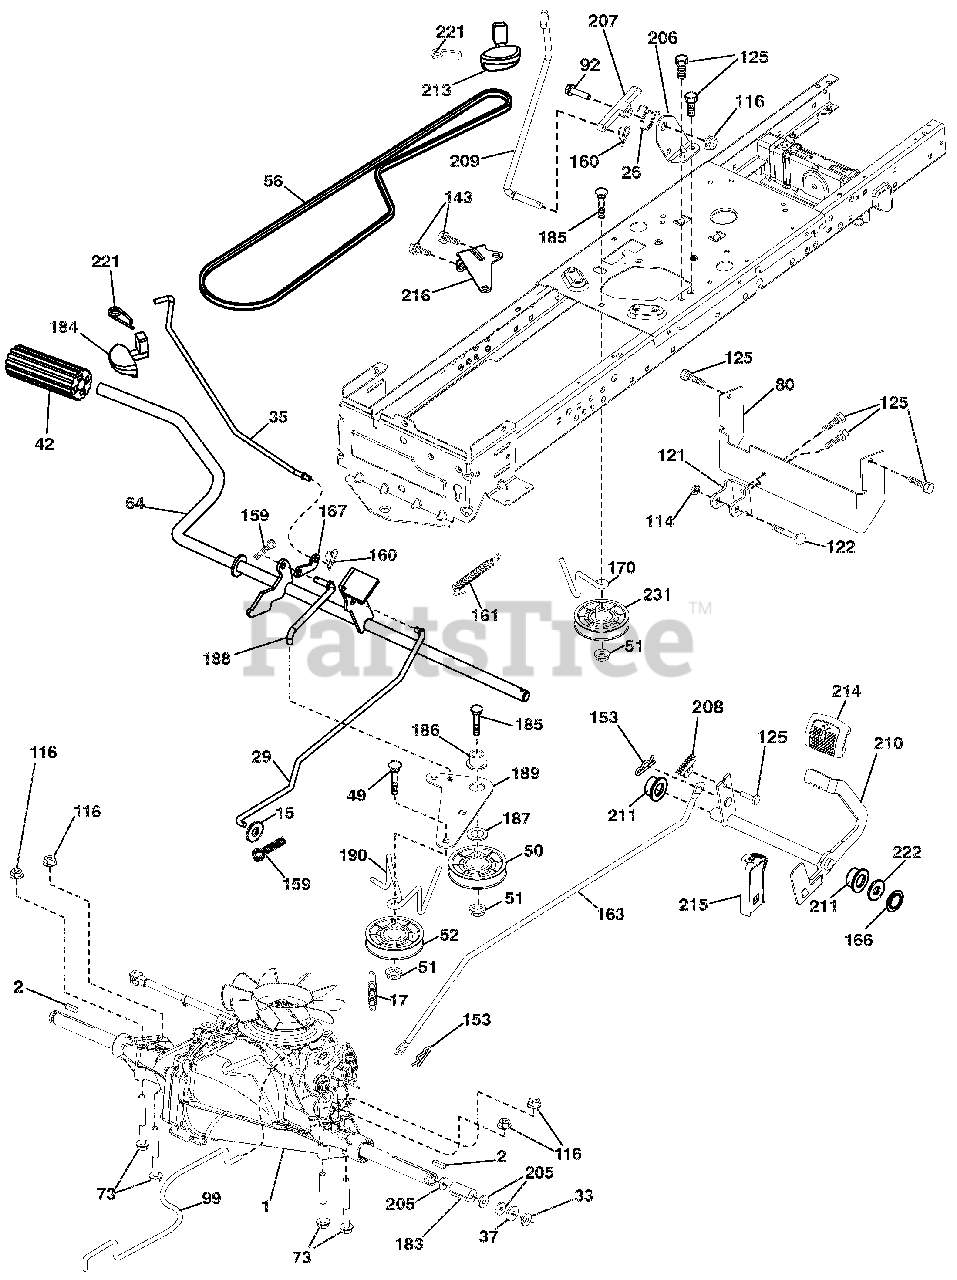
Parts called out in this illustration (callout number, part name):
1	Transaxle, Hydro T2-AABC-1X2B-1GX1(Order Parts From Transaxle)
2	KEY.SQUARE.2.0 X .1845/.1865
15	WASHER.13/32 X 13/16 X 16 GA.
17	SPRING.BRAKE.GT.TEX
26	SPRING.RETURN.CRUISE
29	ROD.BRAKE.T2.TEX
33	E-RING.#5133-75
35	ROD.BRAKE.PARKING.LT.TEX
37	WASHER.25/32 X 1 1/4 X 16 GA.
42	COVER.PEDAL.BLK.ROUND
49	BOLT.RDHD.3/8-16UNCX1-3/4.GR5
50	IDLER.FLAT.910"OFFSET
51	Nut, Hex, Flangelock 3/8-16
52	IDLER.V-GROOVE.910"OFFSET
56	V-BELT.GROUND DRIVE.90.00
64	SHAFT ASM.PEDAL.BRK.CNTRL.PCH
73	BOLT.HEX.FLGHD.5/16-18.GR.5
80	STRAP.TORQUE.FS.T2
92	Bolt, Hex Head 5/16-18 x 1-1/4
99	ROD.ASM.BYPASS.SPRING.T2.FS
114	Locknut, Washer Insert 5/16-18
116	Nut, Lock Hex Flange 5/16-18 u
121	BRACKET.STRAP.TORQUE.T/A.3500
122	BOLT.5/16-18 x 2.50
125	SCREW.5/16-18X3/4.SMGML.TAP/BL
143	SCREW.THDROL.5/16-18 X 1/2TYTT
153	Retainer Spring
159	PIN.COTTER.1/8 X 3/4.CAD.
160	RETAINER.CLIP(M).DIA.290
161	SPRING.RETURN.CLUTCH.6.75
163	ROD.CONTROL.PCH.T2.TEX
166	NUT.PUSH..625.2006
167	LATCH.BRAKE.PARKING
170	KEEPER.CENTER SPAN.1.688
183	SPACER.AXLE.PVST
184	HANDLE.PARKING BRAKE.LTTEX.505
185	BOLT.RDHD.3/8-16UNC X2-3/4 GR5
186	SPACER.RETAINER
187	WASHER.13/32 X 2 X 10 GA.
188	LINK.CLUTCH.GROUND DRIVE
189	BELLCRANK.GROUNDRIVE.NSTG/NSTL
190	KEEPER.BELLCRANK.DRIVE.GROUND
205	WASHER.25/32 X 1-5/8 X 16GA.
206	BRACKET.MOUNT.LATCH.CRUISE
207	LATCH.CONTROL.CRUISE
208	GEAR SECTOR.CONTROL.CRUISE
209	ROD.CONTROL.CRUISE.LT.ELITE
210	ROCKER ASM.PEDAL CONTROL.TEXLT
211	BEARING.NYLON.BLK..629 ID.
213	HANDLE.CONTROL.CRUISE.ELTE.428
214	PEDAL.FORWARD.TEX.GT.428
215	PEDAL.REVERSE.TEX.GT.428
216	BRACKET.PULLEY.IDLER.WTEX
221	RETAINER.SPRING.CLIP.HANDLE
222	WASHER.21/32X1-1/4.10GA.N/PLTD
231	IDLER.V-GROOVE.1.688"OFFSET
